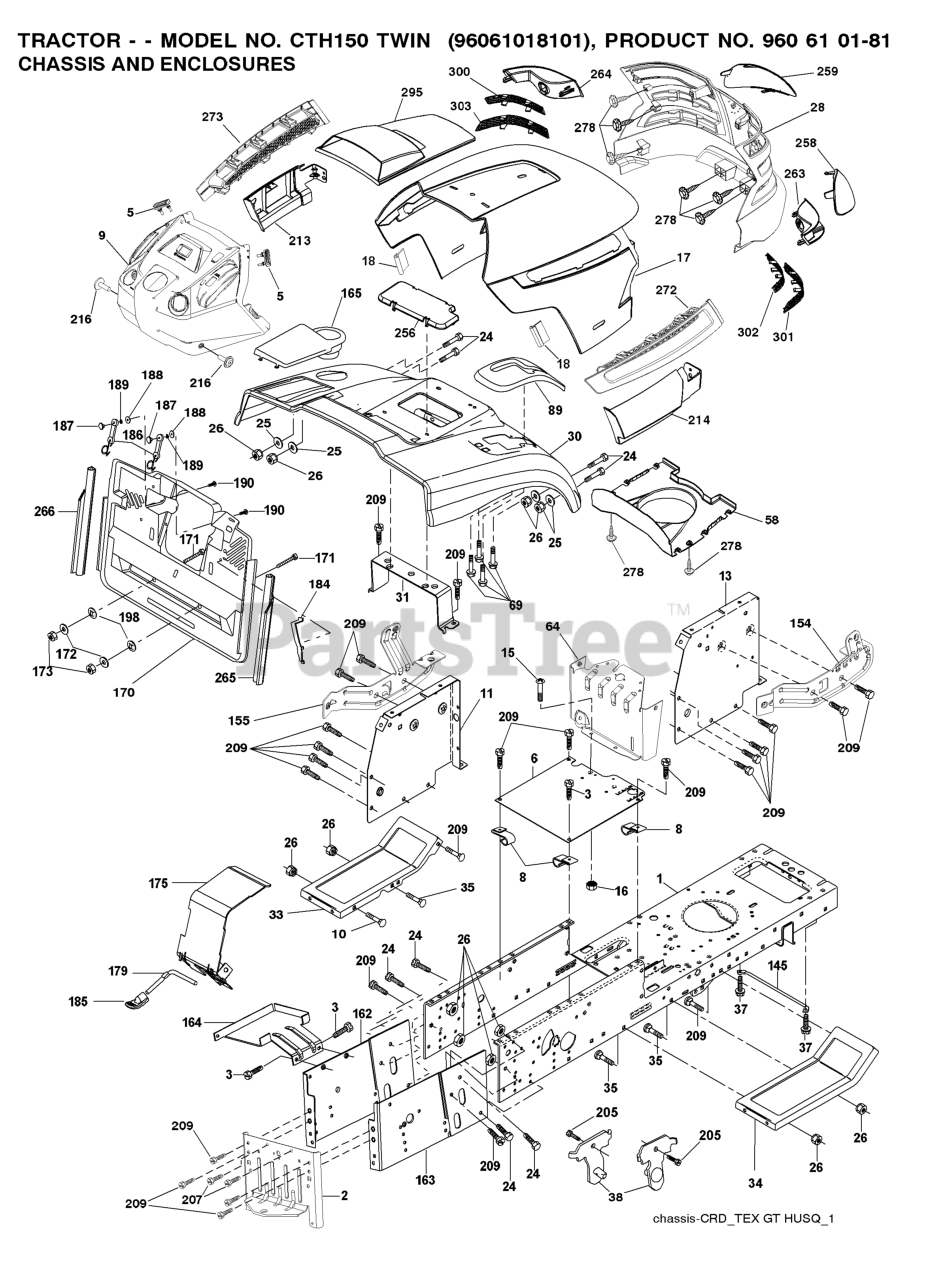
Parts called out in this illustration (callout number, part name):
2	DRAWBAR
3	SCREW 3/8-16X3/4
5	BUMPER DASH
6	PLATE
8	CLIP,INSULATOR
10	BOLT D
11	PANEL DASH LH
13	PANEL DASH RH
15	Screw, Machine, Truss Head 5/16-18 UNC x 3/4
16	NUT
17	HOOD
18	BUMPER.HOOD.TEX.HUSQVARNA
25	WASHER
26	NUT
28	GRILL.ASM.HUSQ.TG/CRD.W/TRIM
30	CONSOLE.CRD.AUTO.GRY
31	BRACKET SUPPORT FENDER
33	FOOTREST PNT LH
34	FOOTREST PNT RH
37	Screw 5/16-18 x 1/2 Hex, Self Tapping 5/16-18 x 1/2
38	BRACKET ASM PIVOT MOWER REAR
58	AIR.DUCT.TEXGT.HUSQ.31
69	SCREW.HI-LO.CONSOLE
89	CONSOLE.CRD.AUTO.GREY.2005
145	ROD.PIVOT.HOOD
162	BRACKET
163	BRACKET EXTEN CHASSIS RH CRD
165	RP.COVER.BATTERY.CRD.GREY
172	WASHER
175	DOOR TRAP
179	ROD PIVOT FBI
184	BRACKET.ACTUATOR.BAGGER.SRD
186	LATCH ASSY
187	WELDNUT
189	LOCKWASHER #10
190	SCREW
207	SCREW, 5/16-18 X 1/2
209	SCREW, 3/8-16X3/4
213	SKIRT.HOOD.SIDE.HUSQ.LH.GREY
214	SKIRT.HOOD.SIDE.HUSQ.RH.GREY
216	SCREW 14-20 X 5/8
256	COVER FENDER CRD
258	LENS.RH.TEX.GT.HUSQ.CL
259	LENS.LH.TEX.GT.HUSQ.CL
263	BEZEL.RH.TEX.GT.HUSQ
264	BEZEL.LH.TEX.GT.HUSQ
265	SEALING
266	SEALING
272	VENT.SIDE.HOOD.HUSQ.RH.GREY
273	VENT.SIDE.HOOD.HUSQ.LH.GRAY
278	SCREW
295	VENT.ASM.HOOD.TOP.TEX.
300	INSERT.HEX.GRILL.HUSQ.
301	INSERT.HEX.GRILL.HUSQ.GREY
302	INSERT.HEX.GRILL.HUSQ.
303	INSERT.HEX.GRILL.HUSQ.
